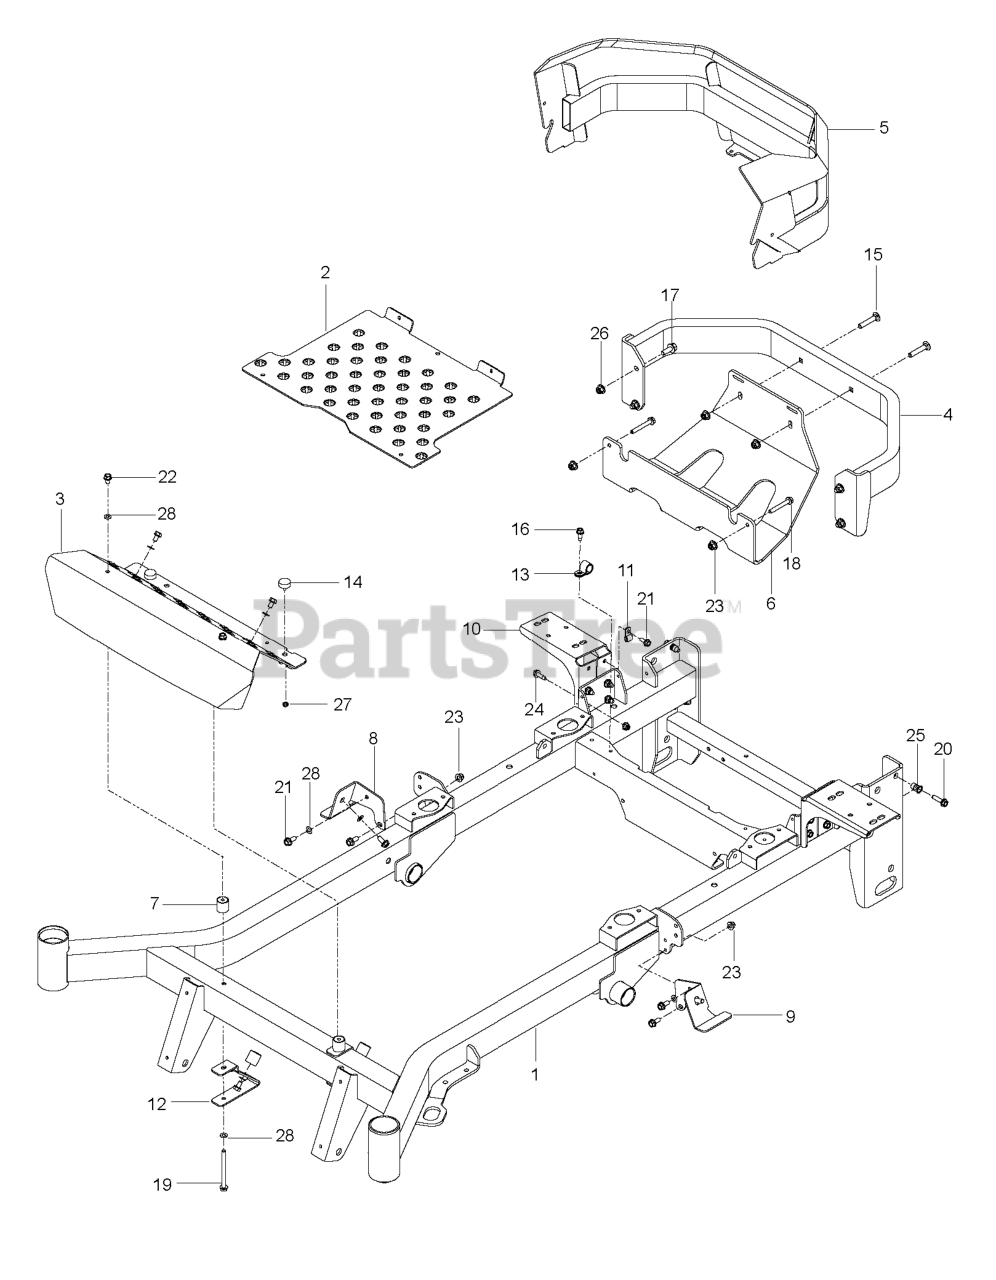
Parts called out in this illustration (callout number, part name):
74	Screws
75	Washers
165	Nuts
267	Screws
318	Screws
318A	Screws
332	Nuts
526	Screws
635	Spark Plugs
695	Screws
934	Screws
1005	Fans
